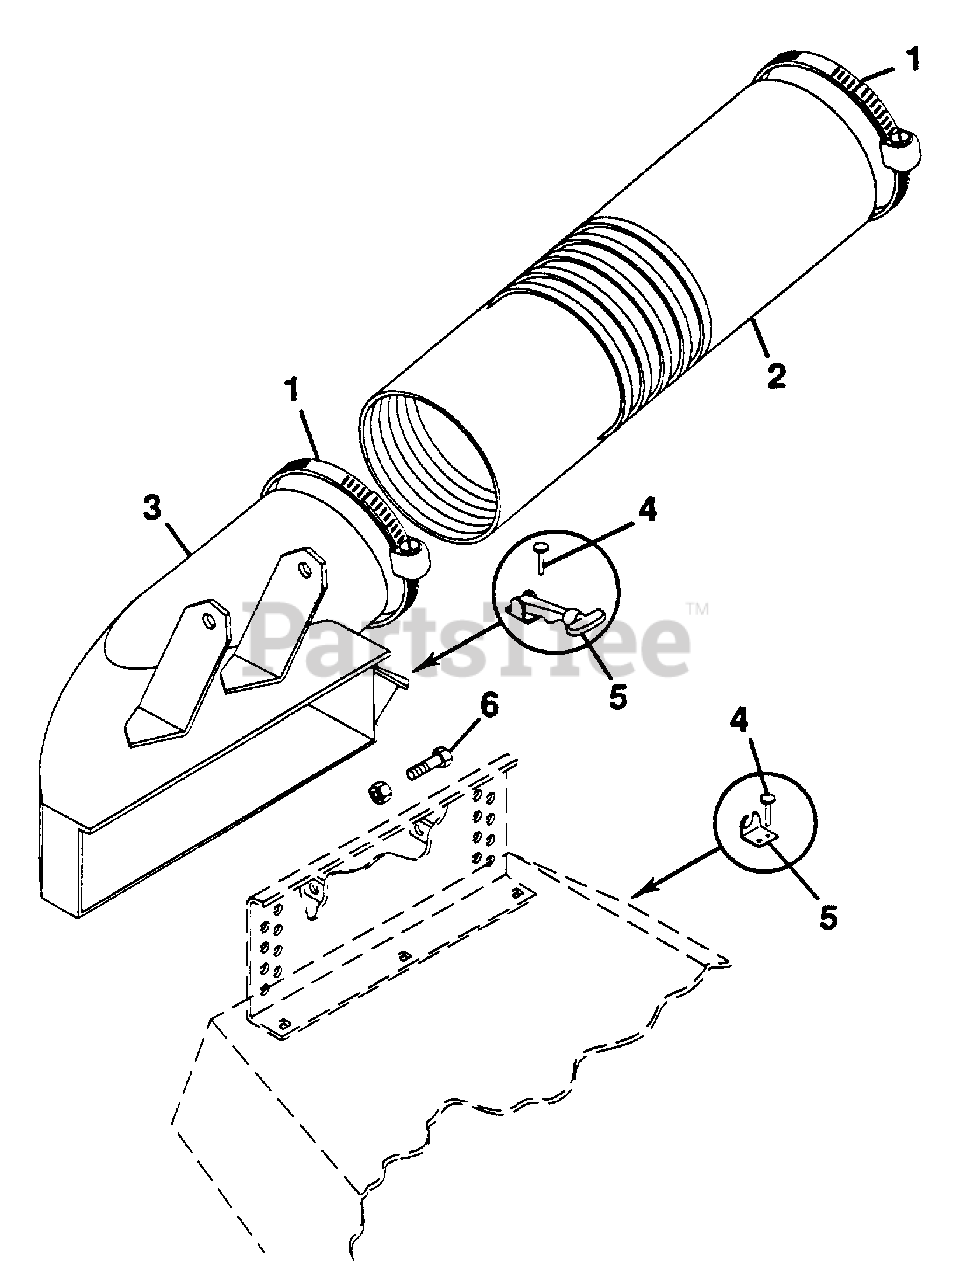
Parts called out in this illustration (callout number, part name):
1	Clamp
2	Hose, Mower to Blower
3	Weldment, 60" Boot
4	Rivet, Dome Head
5	Latch, Flexible Draw
6	Bolt, Hex 3/8-16x1.50
